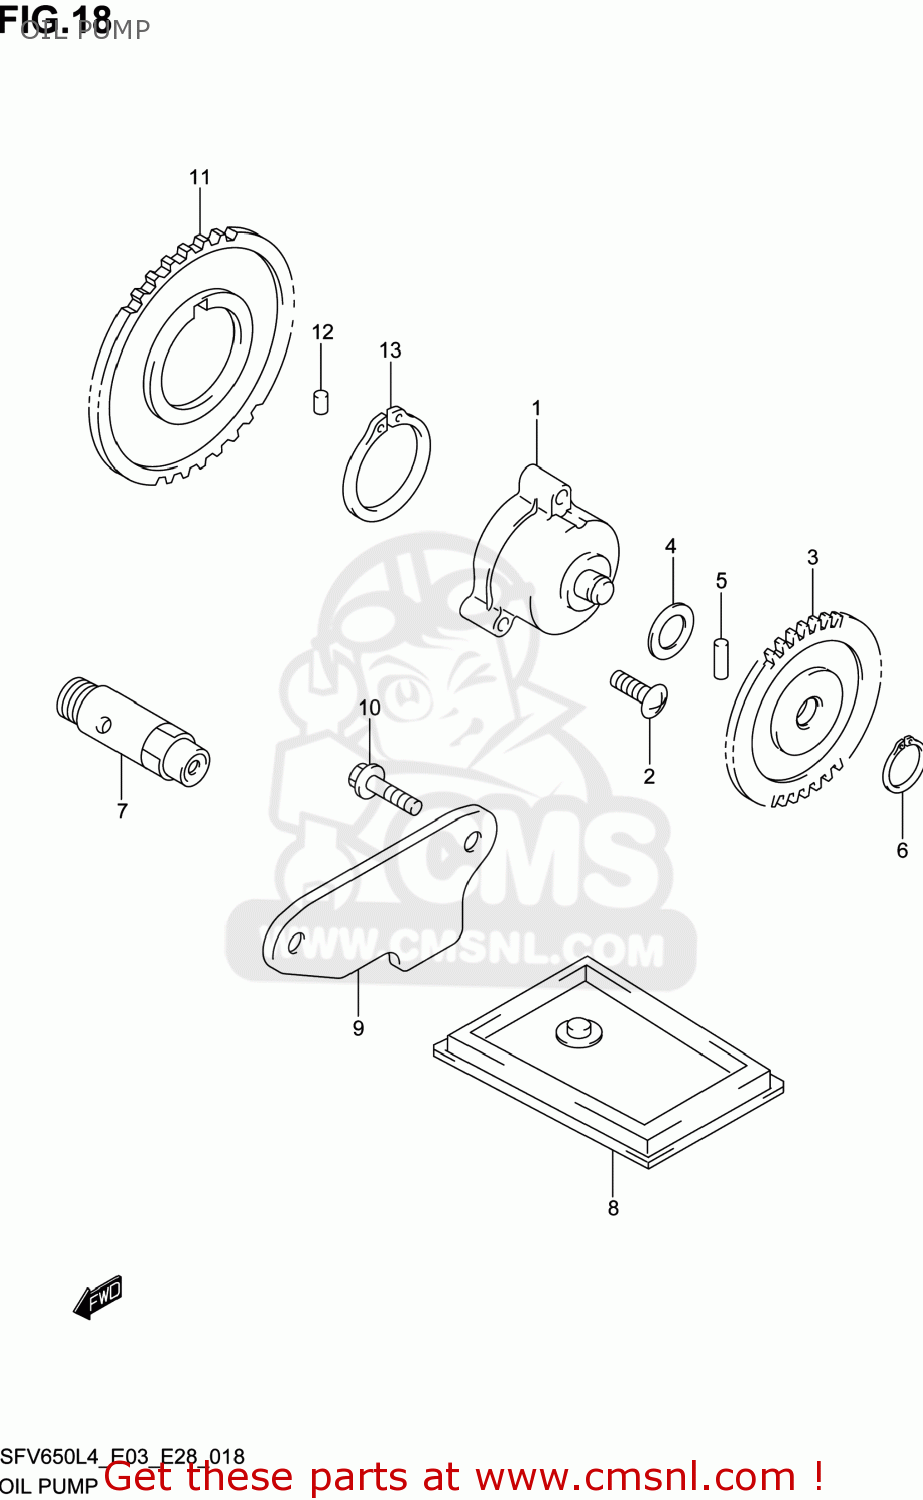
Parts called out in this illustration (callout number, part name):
1	PUMP ASSY,ENGINE OIL
2	BOLT
3	GEAR,ENG OIL PUMP DRIVEN
4	SHIM(10X18X0.5)
5	PIN(4X18.5)
6	CIRCLIP
7	VALVE ASSY,OIL RELIEF
8	STRAINER,ENGINE OIL
9	CAP,OIL STRAINER
10	BOLT
11	GEAR,ENG OIL PUMP DRIVE
12	PIN(6X6)
13	CIRCLIP
